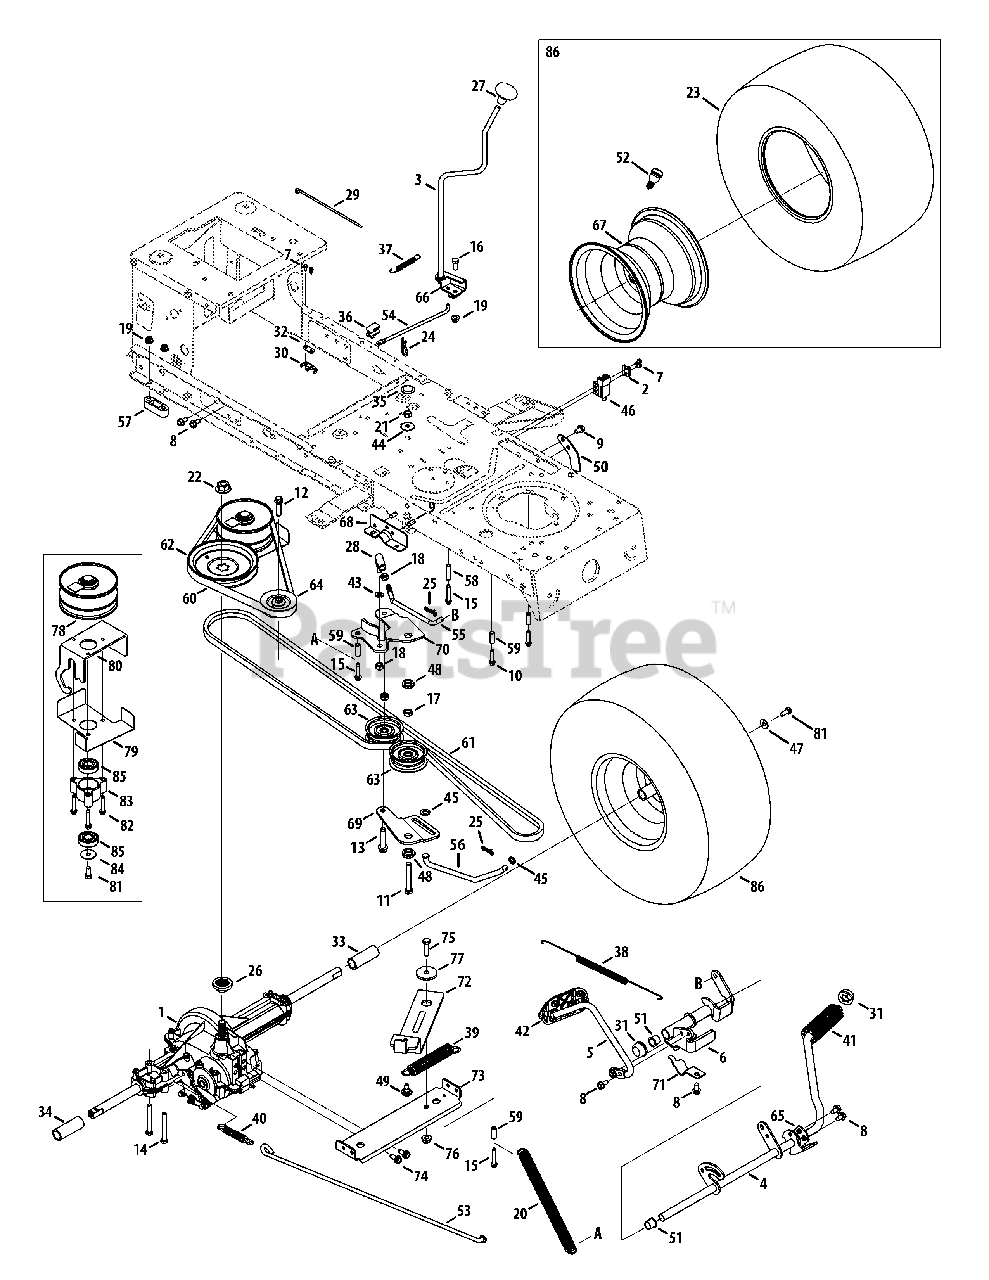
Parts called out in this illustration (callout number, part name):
1	Transmission Drive Asssembly
2	Plate Switch
3	Lever Asm, Shaft
4	Pedal Asm, drive, autodrive
5	Pedal Asm, control, autodrive
6	Bracket Asm, pedal, autodrive
7	Screw, ab, #8-18, 0.500
8	Screw, tt, 5/16-18, .750
9	Screw, tt, 5/16-18, 0.625
10	Screw, tt, 1/4-20, 1.250
11	Screw, 3/8-16, 2.50, Gr5, Std
12	Screw, ttsems, 3/8-16, 1.500
13	Screw, tt, 3/8-16, 1.750
14	Screw, 5/16-18, 3.50, Gr5, Std
15	Screw, tt, 1/4-20, 1.625
16	Screw, 5/16-18, .75, Gr5, Std
17	Nut, jam, 7/16-20, Gr2
18	Nut, hex, 3/8-24, Gr5
19	Nut, flglk, 5/16-18, Grf, nylon
20	Spring, Extension, .56 x 12.05 x .068
21	Nut, hexlck, 3/8-16, cntrlck
22	Nut, flg, 9/16-18, Gr2
24	Pin, cotter Int- .125 Dia
25	Pin, cotter, bow-Tie 72
26	Hub, Pulley, 5/8 Spline
27	Knob, Shaft
28	Ball, joint
29	Cable, tie, 3/16 X .05 X 7.4
30	Switch, Spring, short
31	Cap, push 5/8
32	Plate, Insulator Nut
33	Sleeve, .758 X .821 X 3.3125
34	Sleeve, .758 X .821 X 2.4375
35	Plug, Deck Hole, 7/8
36	Bearing, Shift Plate
37	Spring, ext, .38 Od X 3.25 Lg
38	Spring, extn, .70 Dia X 12.00 Lg
39	Spring, extn, .97 Od X 6.18 Lg
40	Spring, extn, .59 Od X 4.00 Lg
41	Pad, foot, 4.0 Long
42	Pad, control
43	Washer, lock, 3/8, Regular Duty
44	Washer, Flat, .406 x 1.920 x .060
45	Washer, flat, .375 X .738 X .063
46	Switch Interlock
47	Bell Washer, .340 x .872 x .060
48	Spacer, shldr, 1.00 X .38 X .38
49	Screw, shldr, .43x.29, Tt, 5/16-18
51	Bearing, Flange, .630 Idx .695 Od X .60
52	Valve, tubeless Air
53	Rod, brake, Transmission
54	Rod, shift, Stretch
55	Rod, adj, Idler, 3/8
56	Rod, trans, footpedal Bypass
57	Spacer, T-Axle .68
58	Spacer, .260 X .372 X 1.420 Lg
59	Spacer, .260 X .375 X 1.030 Lg
60	Belt, V-Type, 5l X 40.9 Lg Poly
61	Belt, V-Type, 5l, 90.93, Poly
62	Pulley, V-Type, 7.25 Dia Spun
63	Pulley, Idler, flat 2.75 Od
64	Pulley, Idler, v-Type X 3.06
65	Bracket, pedel, support
66	Bracket, Shaft, adj
67	Rim Asm 8.0 X 7.0 X .750 Id
68	Bracket, ped, frame Rh
69	Bracket, Idler, center Dbl
70	Bracket, Idler, dbl Autodrive
71	Bracket, supt, pedal Stap
72	Bracket Asm, Idler
73	Bracket Asm, autodrive
74	Screw, tt, 5/16-18, 0.750
75	Screw, 3/8-16, 1.25, Gr5, Std
76	Nut, flglk, 3/8-16, Grf, nylon
77	Spacer, shoulder, .8840 X .190
78	Pulley Asm, var Speed, 4.75 Od
79	Keeper Asm, belt
80	Bracket Asm, Variable
81	Screw, 5/16-24, 750, Gr5, Lock
82	Screw, tt, 1/4-20, 1.500
83	Cup, Bearing
84	Washer, flat, .330 X 1.25 X .06, Ht
85	Bearing, ball, 17x40x12, 6203
86	Wheel, 20 x 8 x 8
